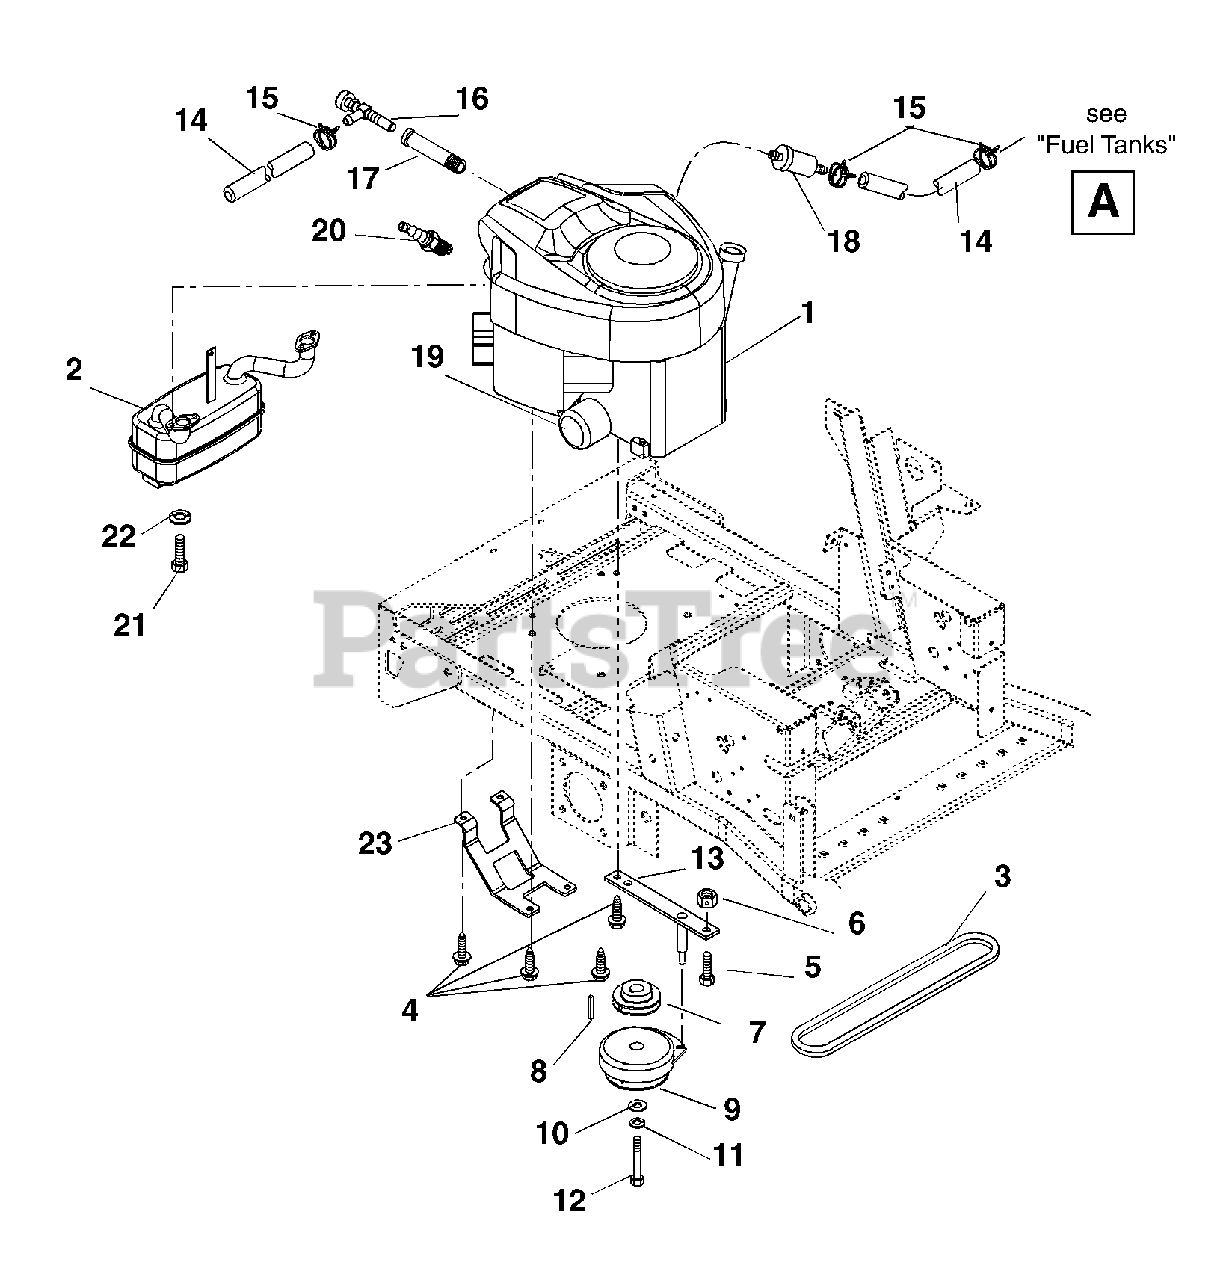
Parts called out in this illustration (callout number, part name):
1	Engine, 20 HP Briggs & Stratton Intek 6-Pin
2	Muffler Assembly
3	V-Belt, A-Section 28.29 x .531
4	Screw-Tapping Hex-Washer-Head .38-16 x 1.25
5	Bolt-Hex .31-18 x 1.75 Grade 5
6	Nut-Locking-Center .31-18
7	Pulley-4.46 Dia. x 1.12 Bore
8	Key-Square .25 x 1.00 x .25
9	Clutch, Electric
10	Washer-Flat-Steel .515 x 1.625 x .250
11	Washer-Locking .44 x .109
12	Bolt-Hex .44-20 x 3.00 Grade 5
13	Anchor-Clutch
14	Gas Line-Bulk .25" I.D.
15	Hose-Clamp
16	Cock-Oil Drain
17	Adapter-Oil Drain
18	Fuel Filter
19	Oil Filter
20	Plug, Spark
21	Screw-Socket Head M8 x 1.25 x 20
22	Washer-Locking .31 x .078 Regular
23	Guard, Muffler
